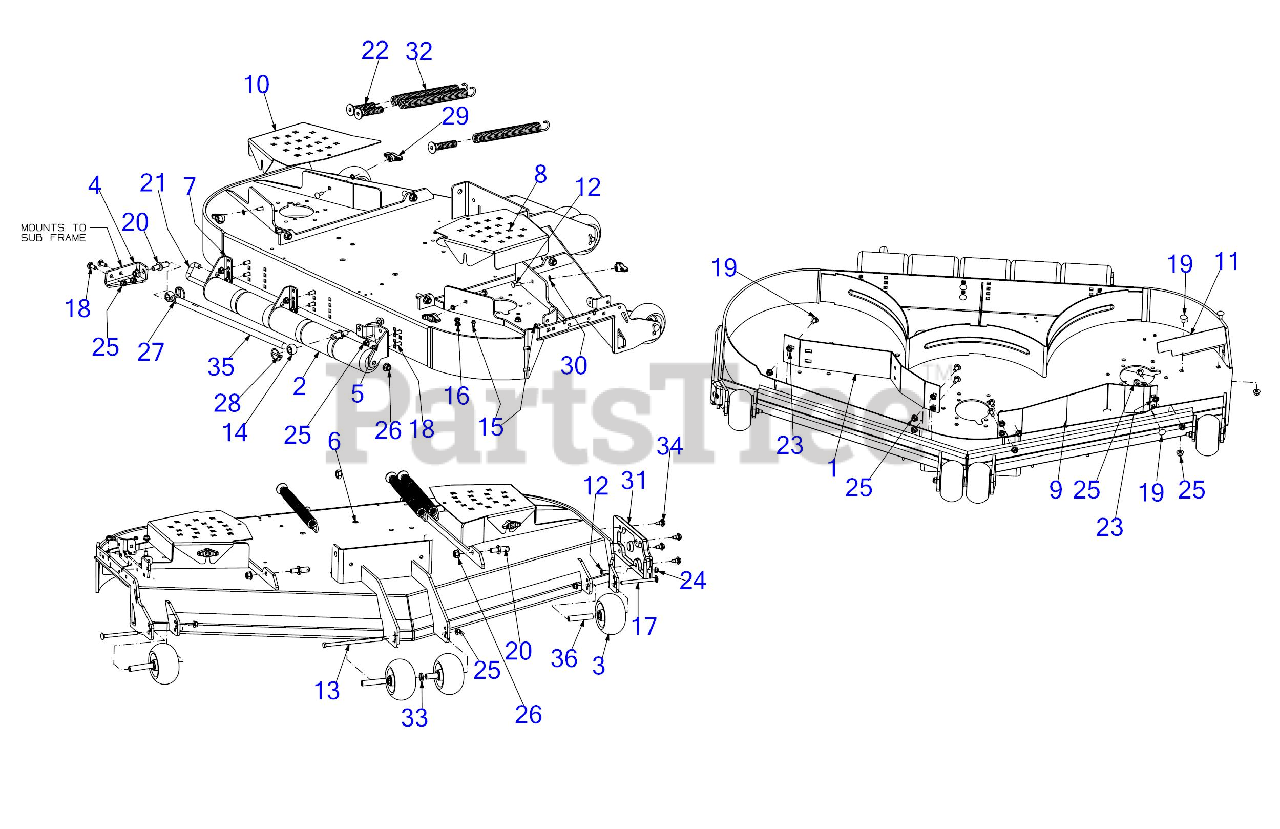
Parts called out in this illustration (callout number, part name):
2	ROLLER ASSEMBLY
3	5" DIA DECK WHEEL COMPLETE
12	CARRIAGE BOLT 5/16-18 x 1.00
13	SCREW 3/8-16 x 7.25 GR5
14	BOLT 5/8-16 x 2.63
15	SCREW 1/4-20 X.500
16	SCREW 5/16-18 x .500
17	CARRIAGE BOLT 3/8-16 x 4.25 GR5
18	CARRIAGE BOLT 3/8-16 x 1.00 GR5
19	CARRIAGE BOLT 3/8-16 x .75
21	REAR ROLLER PIN
22	SPRING INSERT SCREW
24	FLANGE LOCK NUT 5/16-18
27	HEX NUT
29	WING KNOB 5/16-18
31	DECK SKID PLATE (LH)
32	EXTENTION SPRING 1.20 x 11.35
33	FLAT WASHER .632X1.00X.16
34	SHOULDER SCREW .43X.29X5/16-18 TT
36	WHEEL SPACER .38ID x 3.04LG
